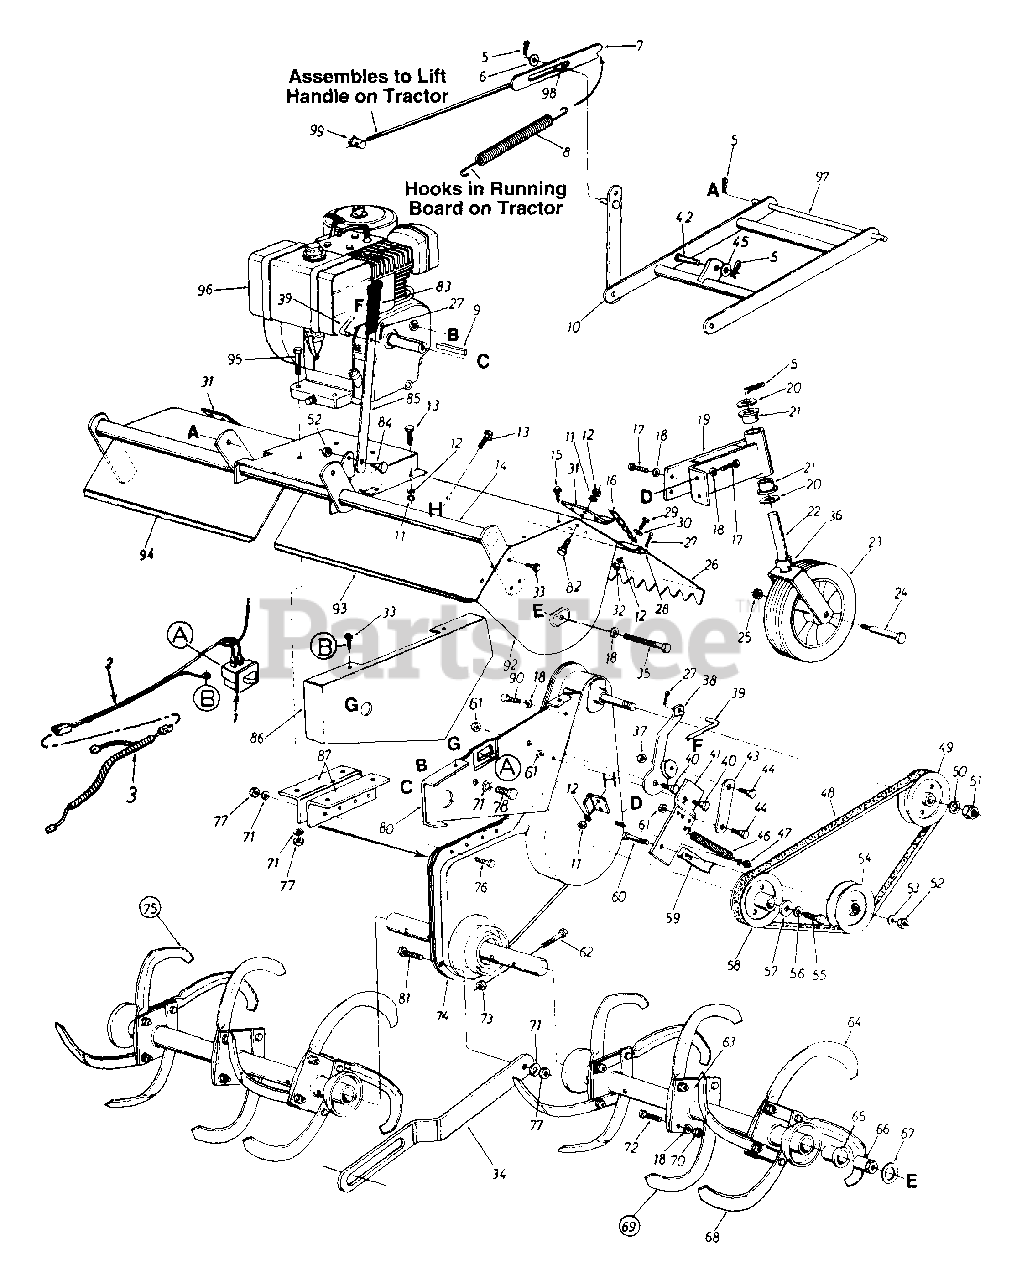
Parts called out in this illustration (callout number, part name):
1	Safety Switch
2	Wire Harness
3	Adapter Harness
5	Internal Cotter Pin
6	Fl-Wash. 1/2" I.D. x .93" O.D.
9	Sq. Key 1/4" x 1/4" x 2.00" Lg.
12	L-Wash. 1/4" I.D.
13	Hex Bolt 1/4-28 x .62" Lg.
16	#2 Dog Chain x 20" Lg.
17	Hex Wash. Hd. Self-Tap Scr. 3/8-24 x .75" Lg.
18	L-Wash. 3/8" I.D.
19	Swivel Wheel Support
20	Fl-Wash. 3/4" I.D. x 1.50" O.D.
21	Flange Bearing 3/4" I.D. x 1.00" O.D.
22	Swivel Wheel Caster
23	Wheel Assembly 10.0 x 2.75
24	Shoulder Bolt .623" I.D. x 3.62" Lg.
25	Hex Cent. L-Nut 7/16-14 Thd.
28	L.H. Flap Rod
28	R.H. Flap Rod
29	Hex Bolt 1/4-20 x .62" Lg.
30	Fl-Wash. 1/4" I.D.
33	Hex Wash. Hd. Self-Tap Scr. 1/4" x .62" Lg.
34	Stabilizer Link
35	Hex Bolt 3/8-16 x 1.25" Lg.
36	Spacer .752" I.D. x 1.25" O.D.
37	Hex Cent. L-Nut 5/16-18 Thd.
40	Shoulder Bolt 7/16" Dia. x 1.75"
45	Fl-Wash. .50" I.D. x 1.0" O.D. x .06
46	Extension Spring .62" O.D. x 6.12" Lg.
47	Hex Crown Nut 3/8-24 Thd.
48	V-Belt (Kevlar)
49	1/2" "V"-Pulley 4.75" O.D. x .625" Bore
50	L-Wash. 5/8" I.D.
51	Hex Ins. L-Nut 5/18-16 Thd.
52	Hex Cent. L-Nut 3/8-16 Thd.
53	Fl-Wash. 3/8" I.D.
54	Idler Pulley 4.0" O.D.
55	Hex Bolt
56	L-Wash. 7/16" I.D.
57	Fl-Wash. 7/16" I.D. x 1.38"
58	1/2" "V"-Pulley .475" O.D. x 1.00" Bore
61	Hex Cent. L-Nut 5/16-18 Thd.
62	Hex Bolt 7/16-14 x 2.00" Lg.
65	Flange Bearing 1.00" I.D.
66	Spacer
67	Thrust Wash. 1/2" I.D. x 1.55"
68	Tine - R.H.
69	Tine Assembly Comp. - L.H.
70	Hex Nut 3/8-24 Thd.
71	L-Wash. 5/16" I.D.
72	Hex Bolt 3/8-24 x 1.5" Lg.
73	Hex Cent. L-Nut 7/16-14 Thd.
77	Hex Nut 5/16-18 Thd.
78	Hex Bolt 5/16-24 x .62"
80	Clutch Support Bracket
81	Shld. Bolt .435" Dia. x .265" 5/16-18 Thd.
82	Hex Bolt 1/4-28 x .75" Lg.
83	Plastic Grip
84	Shoulder Bolt .498" Dia. x .212" Lg.
87	Engine Mounting Bracket
90	Hex Bolt 3/8-16 x .62" Lg.
92	L.H. - Side Plate
96	8 H.P. Engine
97	Hitch Rod
98	Push Bar Sleeve .503" I.D. x .624" O.D.
99	Ferrule
